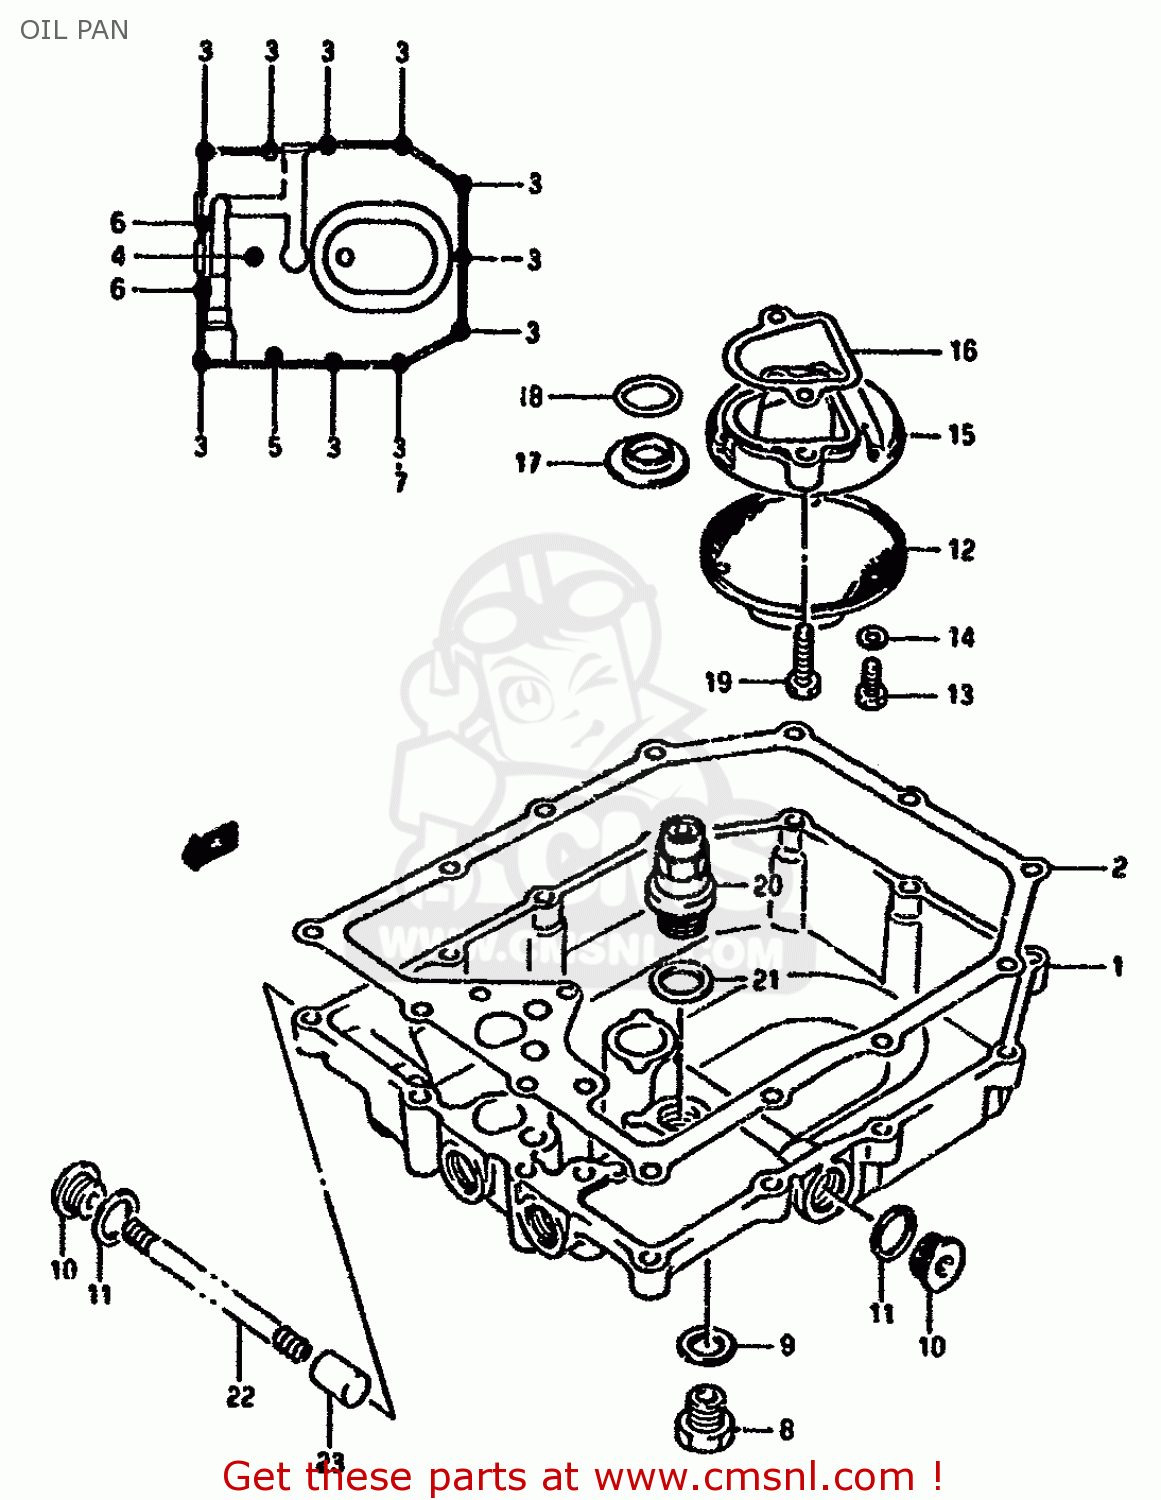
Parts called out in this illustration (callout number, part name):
1	PAN,OIL
2	GASKET,OIL PAN (NAS)
3	BOLT
4	BOLT
5	BOLT
6	BOLT
7	GASKET(5.8X11X1.2) (NAS)
8	PLUG
9	GASKET(14X19.2X2) (NAS)
10	PLUG
11	GASKET(16X22X2) (NAS)
12	STRAINER,ENGINE OIL
13	BOLT
14	WASHER,LOCK
15	PROTECTOR,OIL STRAINER
16	O-RING
17	GASKET,OIL OUTLET (NAS)
18	O RING(D:3.2,ID:17.8)
19	BOLT
20	VALVE ASSEMBLY,OIL RELIEF
21	GASKET(16X22X2) (NAS)
22	SPRING
23	PLUNGER,OIL CONTROLL
